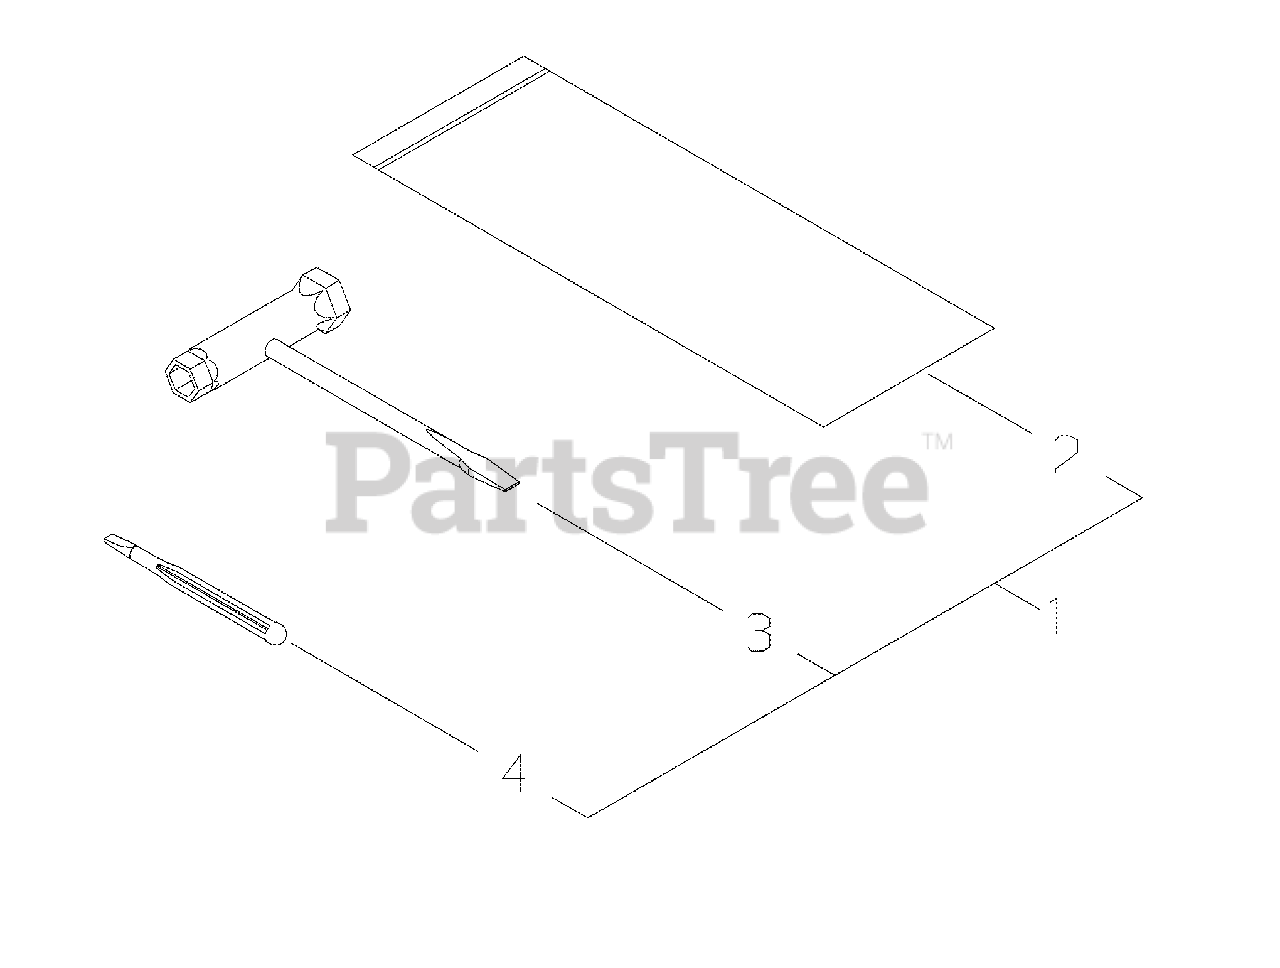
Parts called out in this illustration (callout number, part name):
1	TOOL KIT
2	BAG, TOOL
3	T-WRENCH - 13X19mm
4	SCREWDRIVER - PLASTIC
